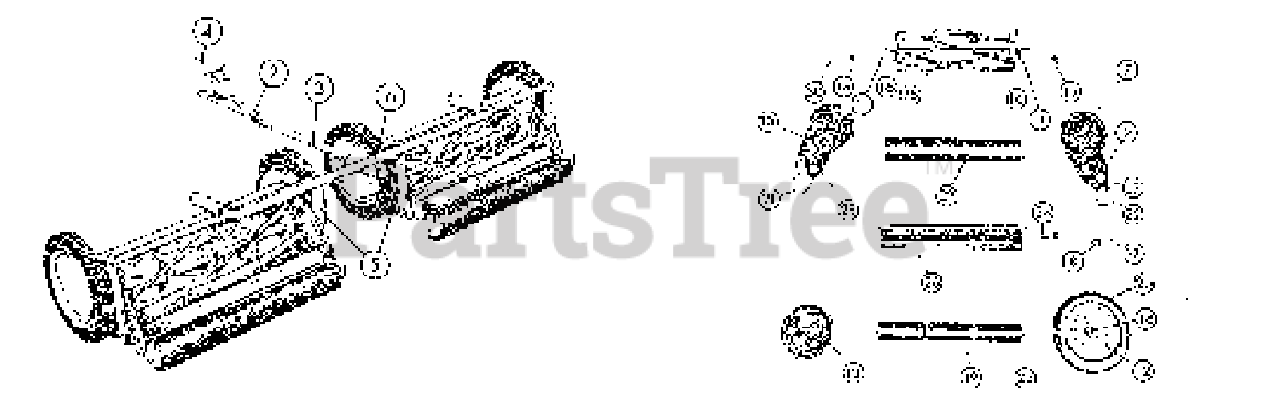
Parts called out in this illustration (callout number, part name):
2	PIN, Tongue
3	TONGUE ASSEMBLY
4	TONGUE EXTENSION ASSEMBLY
5	DRAW BAR ASSEMBLY, Single
6	DRAW BAR ASSEMBLY, Double
7	AXLE, Wheel
8	WASHER, Wheel Retaining
9	CAM, Adjusting
10	BEARING HOUSING
11	PAWL, Driving
12	WHEEL, Internal Gear
14	GEAR, Pinion, L.H.
15	GEAR, Pinion, R.H.
16	BEARING, Reel
17	RING, Retainer
18	BEARING, Wheel
21	ROLLER, Retainer Bracket, L.H.
22	ROLLER, Retainer Bracket, R.H.
23	SHAFT, Roller
24	BUSHING, Hitch
25	REEL ASSEMBLY, 20"
26	BAR ASSEMBLY, Cutter, 20"
27	FRAME ASSEMBLY, Side, R.H.
28	FRAME ASSEMBLY, Side, L.H.
29	BAR ASSEMBLY, Brush, 20"
30	INSERT, Pinion Gear
